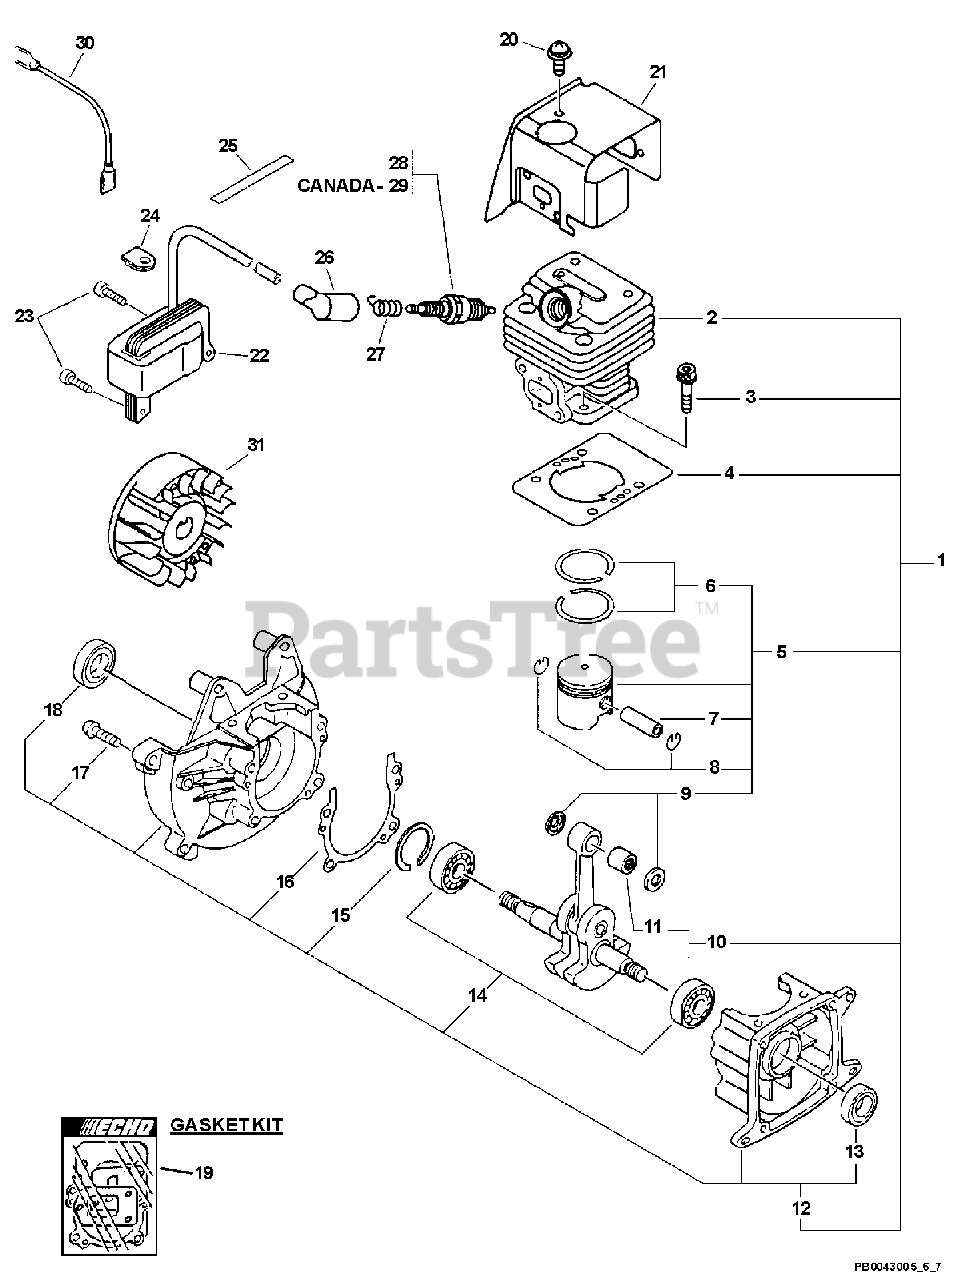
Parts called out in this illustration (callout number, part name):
1	SHORT BLOCK -- SB1062
2	CYLINDER
3	SCREW - 5X22
4	GASKET, CYLINDER
5	PISTON KIT
6	RING, PISTON
7	PIN, PISTON
8	RING, RETAINING
9	SPACER, PISTON
10	CRANKSHAFT ASSY
11	BEARING, NEEDLE - 8
12	CRANKCASE KIT
13	SEAL, OIL
14	BEARING, BALL - 6001C3
15	RING, RETAINING - 28
16	GASKET, CRANKCASE
17	SCREW - 5X25
18	SEAL, OIL - 12
19	GASKET KIT
20	SCREW - 5X10
21	SHIELD, CYLINDER
22	COIL, IGNITION
23	SCREW - 5X16
25	LABEL - SPARK PLUG -- BPM-8Y
26	CAP, SPARK PLUG
27	TERMINAL, SPARK PLUG CAP
28	SPARK PLUG -- BPM-8Y
29	SPARK PLUG -- BPMR-8Y
30	LEAD - IGNITION
31	FLYWHEEL
